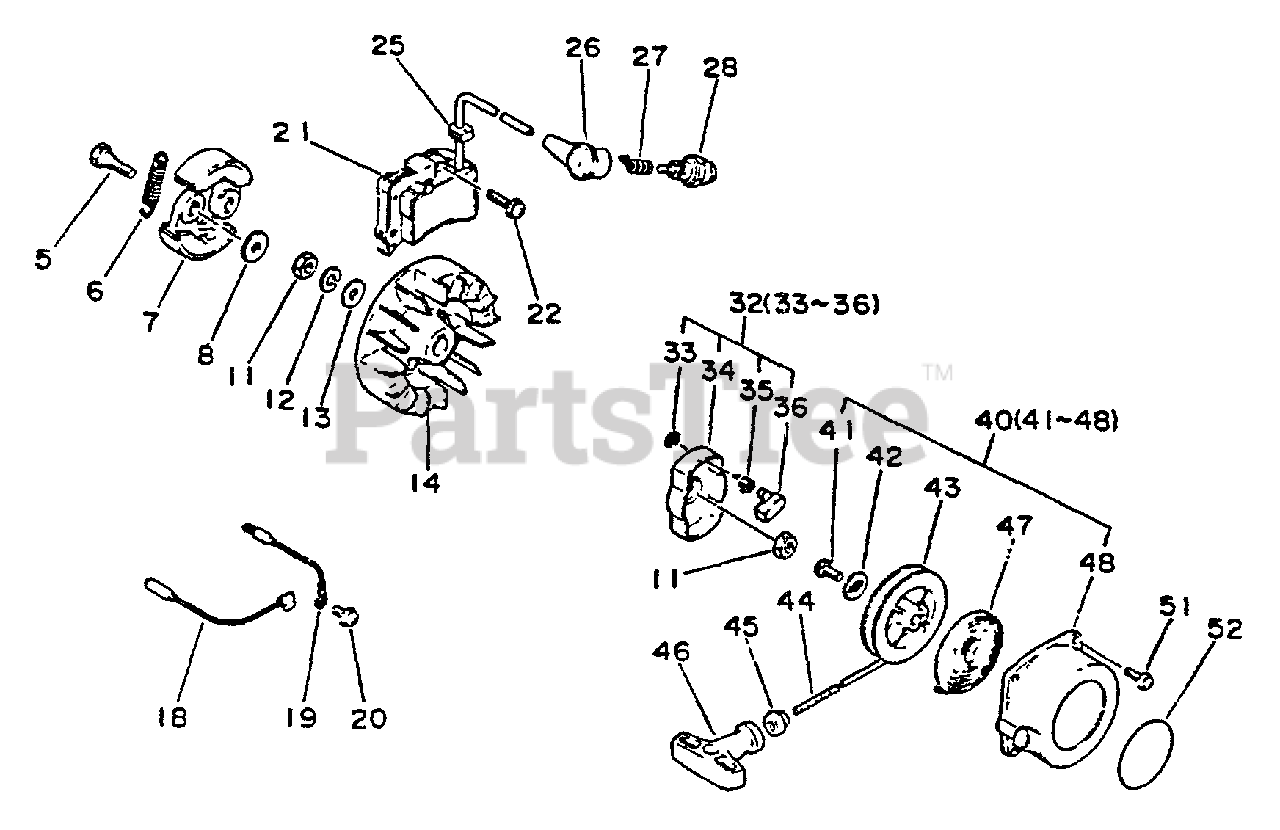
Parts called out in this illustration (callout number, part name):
5	BOLT, CLUTCH
6	SPRING, CLUTCH
7	SHOE, CLUTCH
8	WASHER - 6
12	LOCKWASHER - 5
13	WASHER - 8
14	FLYWHEEL
18	LEAD - GROUND
19	LEAD - GROUND
20	SCREW - 5X10
21	COIL, IGNITION
22	SCREW - 5X20
26	CAP, SPARK PLUG
27	TERMINAL, SPARK PLUG CAP
28	SPARK PLUG -- BPM-7A
28	SPARK PLUG -- BPMR-7A
32	STARTER PAWL ASSY
33	RING, RETAINING - 6
34	CATCHER, PAWL
35	SPRING, RETURN
36	PAWL, STARTER
40	STARTER ASSY
42	WASHER
43	REEL, ROPE
44	ROPE, STARTER - 3.5X850
45	GUIDE, ROPE
46	GRIP, STARTER
47	SPRING, REWIND
48	CASE, STARTER
51	SCREW - 5X14
52	LABEL - ECHO
